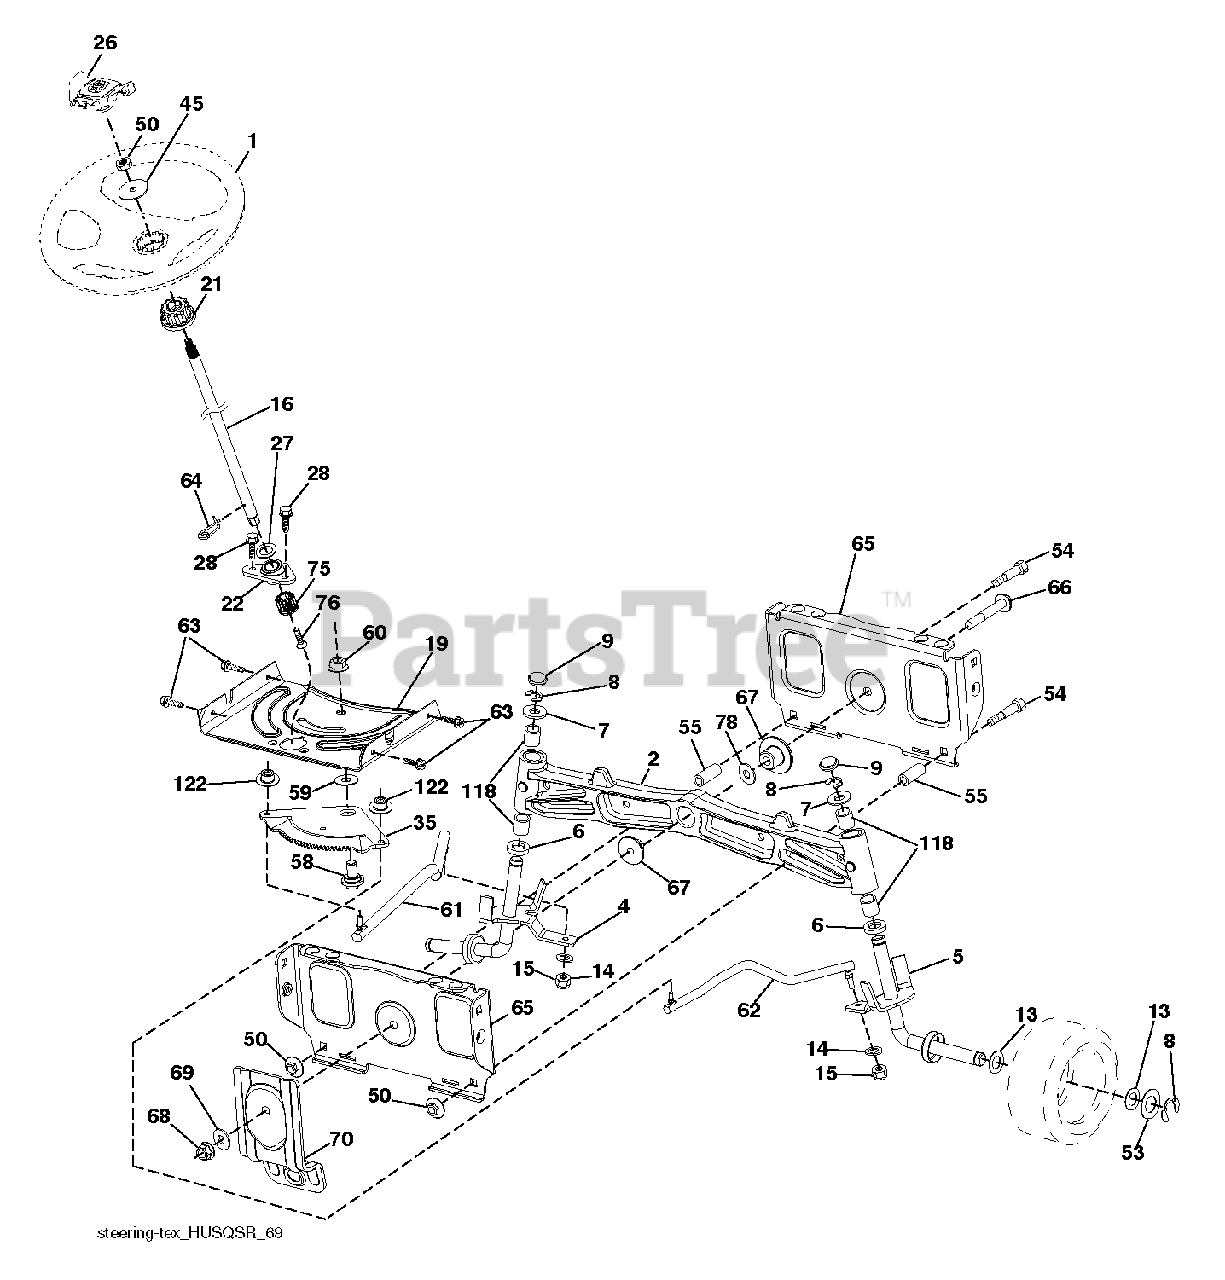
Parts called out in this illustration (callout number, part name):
1	WHEEL.STEER.HUSQ.SR.498.OVMLD
2	AXLE.SVC.ASM CAST IRON.TEX
4	SPINDLE.WELDED.LH.16"TEX
5	SPINDLE.WELDED.RH.16"TEX
6	THRUST WASHER
9	CAP.SPINDLE.BLACK
14	WASHER, LOCK 3/8
15	NUT CROWNLOCK 3/8-24
16	SHAFT.STEERING.2HIGH.SPLND.RAW
19	PLATE.STEER.DDL.NLT/NG
21	ADAPTER.WHEEL.STEER.SPLND.ALUM
22	BEARING.SUBASM.SHAFT.STEER.LOW
26	INSERT.CAP.WHL.STRG.HUSQ.PREM
28	SCREW, 3/8-16X3/4
35	GEAR.SECTOR.PLATE.DDL.
45	WASHER.3/8ID.2-3/8OD.12GA.PLTD
50	NUT LOCK FLG 3/8-16 UNC
53	WASHER.HARDENED
55	SPACER.BRACE.AXLE
58	BOLT.SHOULDER.SECTOR.P
59	WASHER.THURST.SECTOR.S
60	NUT FLANGE LOCK 5/8-11
61	DRAGLINK.LH.ADJUSTABLE.TEX
62	DRAGLINK.RH.ADJUSTABLE.TEX
63	SCREW
64	RETAINER.CLIP.SPRING.S
65	BRACE.AXLE.FRONT.NLT/N
66	BOLT HEX FGHD 7/16-14 X 3 SERR
67	BUSHING.PM.FRONT AXLE
68	NUT.LOCK.FLANGE.7/16
69	WASHER.1.5X.505X.118
70	BRACKET.FRT.DECK.SUSP.RR.MT431
75	PINION.ZINC PLATED
76	SCREW HEAD SOCKET LRVB
78	THRUST WASHER
118	BUSHING, AXLE CAST
122	CAP.GEAR.SECTOR.TEX
